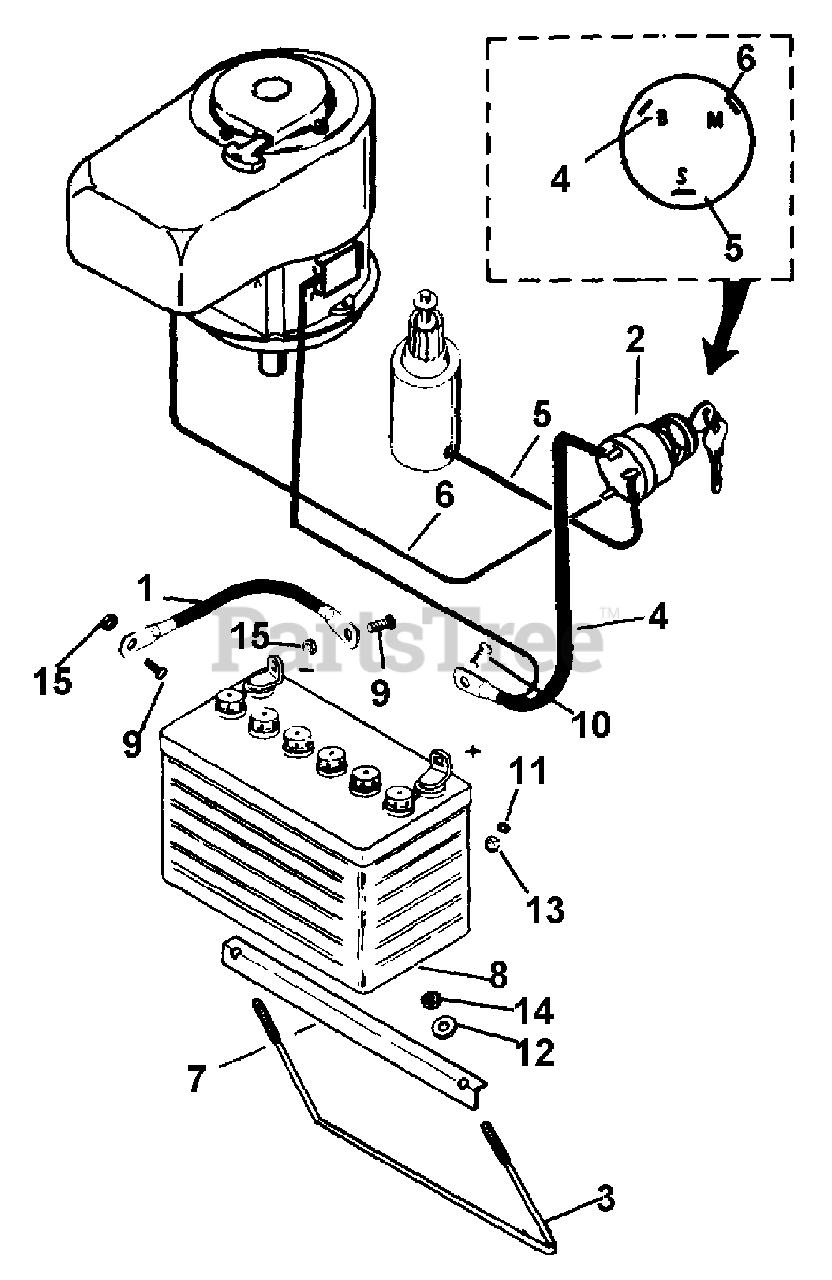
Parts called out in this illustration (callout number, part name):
1	GROUND CABLE
2	IGNITION SWITCH
3	BATTERY CLAMP
6	SHORTING WIRE
7	BATTERY HOLD DOWN
8	BATTERY
9	BLT-HEX .25-20X.63 PL GR2
10	BLT-RDHDSQNK .31-18X.75 GR5 PL
11	WSHR-LK .312X.097 PL HVY
12	WSHR-FL-STL.312X.734X.065PL
13	NUT-HEX .312-18
14	NUT-LK-CTR .250-20 PL
15	NUT-LK-FLG .250-20 PL
